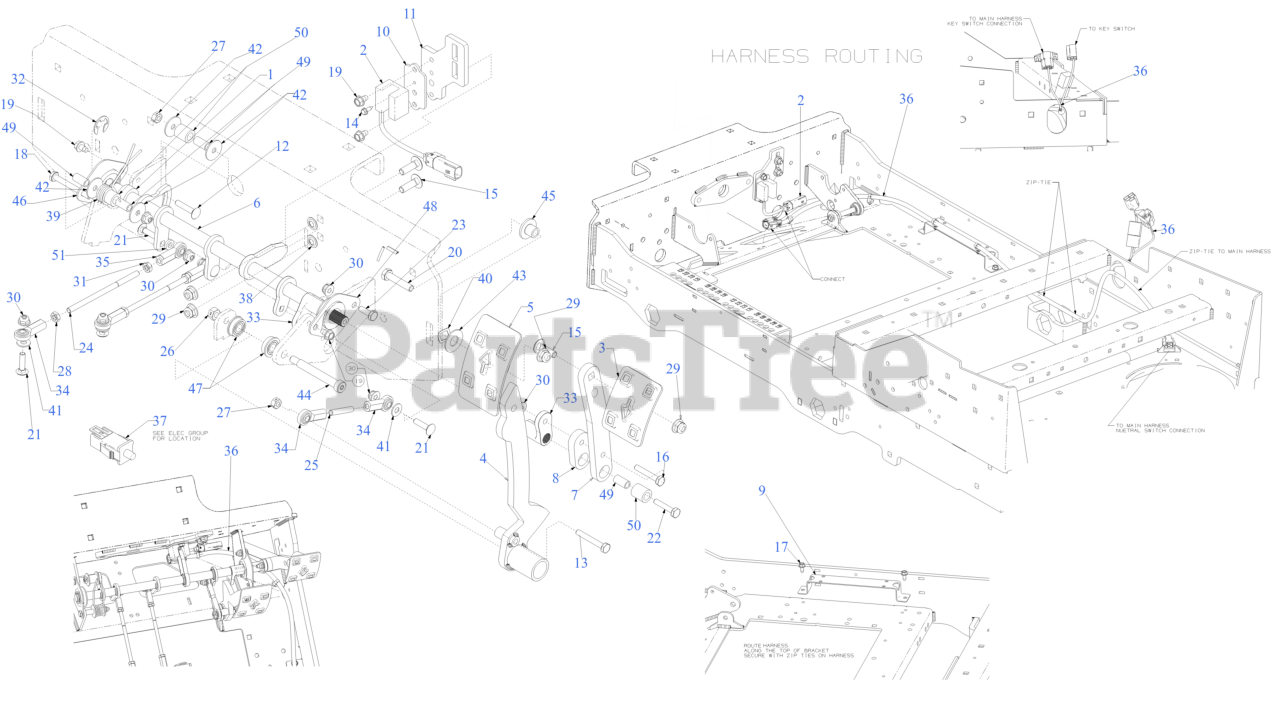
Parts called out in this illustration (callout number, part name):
1	SHAFT COLLAR .625
2	NEUTRAL SENSOR SWITCH
4	FORWARD PEDAL ARM ASSEMBLY
6	ARM ASSEMBLY
7	REVERSE PEDAL PLATE
8	REVERSE PEDAL SPACER
9	HARNESS GUIDE BRACKET
10	REED VANE SENSOR PLATE
11	REED VANE SENSOR PLATE
12	CARRIAGE BOLT 1/4-20 x 1.25 Gr5
13	HEX SCREW 1/4-20 x 1.75
14	HEX SCREW WASHER HD #8-18 x 0.500
15	CARRIAGE BOLT 5/16-18 x 1.00
16	SCREW 1/4-20 x 1.50 GR8
17	SCREW 1/4-20 X.500
18	SCREW 1/4-20 x 2.25 GR5
19	SCREW 1/4-20 x .375
20	SCREW 5/16-18 x 1.5 LG
21	SCREW 1/4-20 x 1 GR5
22	SCREW 1/4-20 x 1.25 GR5
23	SCREW 1/4-20X.75 GR5
24	SPEED CONTROL ROD
25	STUD - 1/4-28
26	HEX NUT CENTER
28	HEX JAM NUT 1/4-28
29	FLANGE LOCK NUT 5/16-18
30	FLANGE LOCK NUT
31	JAM NUT 1/4-28 LH
34	END ROD (RH)
36	PEDAL SWITCH JUMPER
37	PLUNGER SWITCH NO/NC
39	TORSION SPRING
40	WAVE WASHER
41	FLAT WASHER
42	FLAT WASHER
43	FLAT WASHER
44	SHOULDER BOLT .375 x 2.50 x 5/16-18
45	DOUBLE SHOULDER SPACER
46	BALL BEARING
47	FLANGE BEARING
48	BALL BEARING
49	SPACER .260 x .375 x .75
50	SPACER-.375X.625X.600
51	SPACER .25 X .50 X .110
